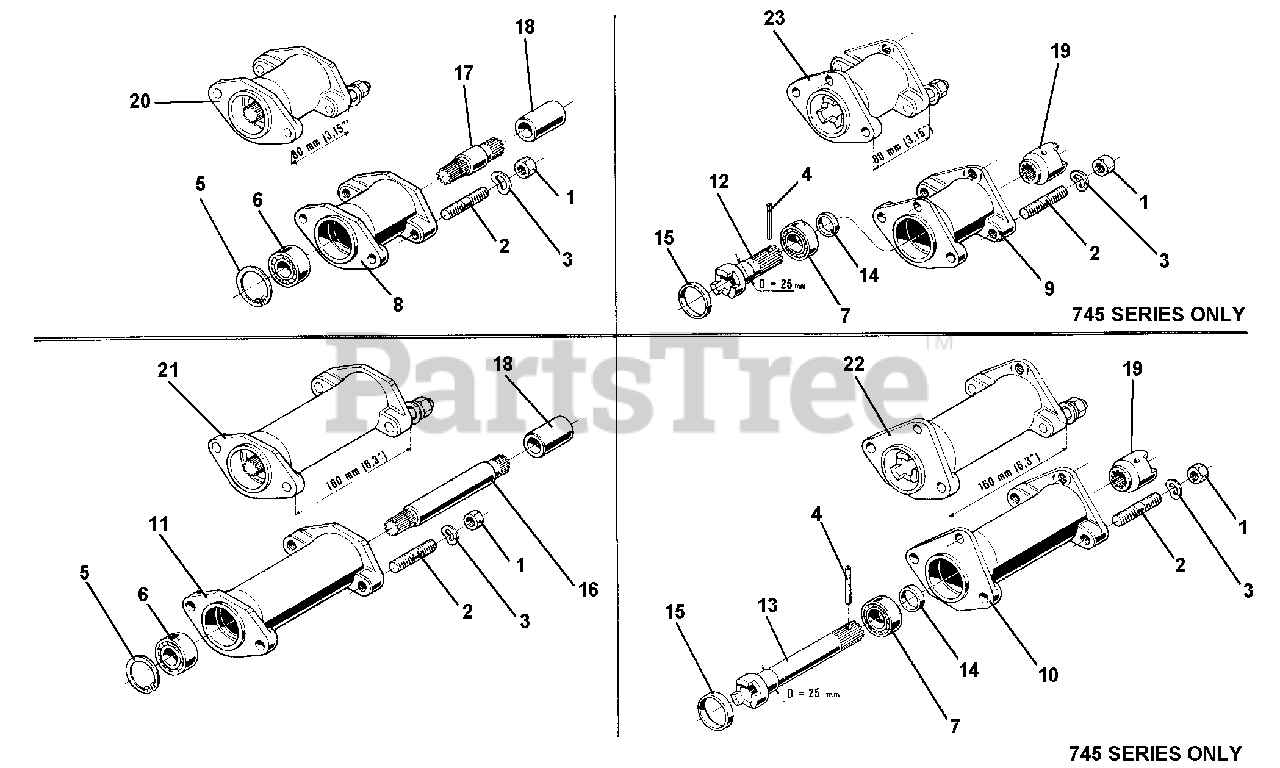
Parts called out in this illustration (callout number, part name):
1	NUT M12 X 1.25 UNI 5587 6S
2	STUD 56XM12X1.25X26XM12X22 8G
3	WASHER, LOCK 13
4	LOCKING PIN 6 X 40
5	CIRCLIP, INTERN. D 47
6	BEARING 20 X 47 X 14 6204 2RS ST
7	BEARING 25 X 47 X 12 2RS 6005
8	EXTENSION, MM 80
9	HOUSING, P.T.O. EXTENSION
10	EXTENSION BODY
11	EXTENSION BODY 160 MM
12	EXTENSION SHAFT
13	EXTENSION SHAFT
14	RING FOR HALF AXLE
15	EXTENSION RING
16	SHAFT FOR EXTENSION 16 CM
18	BUSHING, GROOVED
20	PTO EXTENSION 3"
21	PTO EXTENSION 6"
22	PTO EXTENSION 6" (745 ONLY)
23	PTO EXTENSION 3" (745 ONLY)
